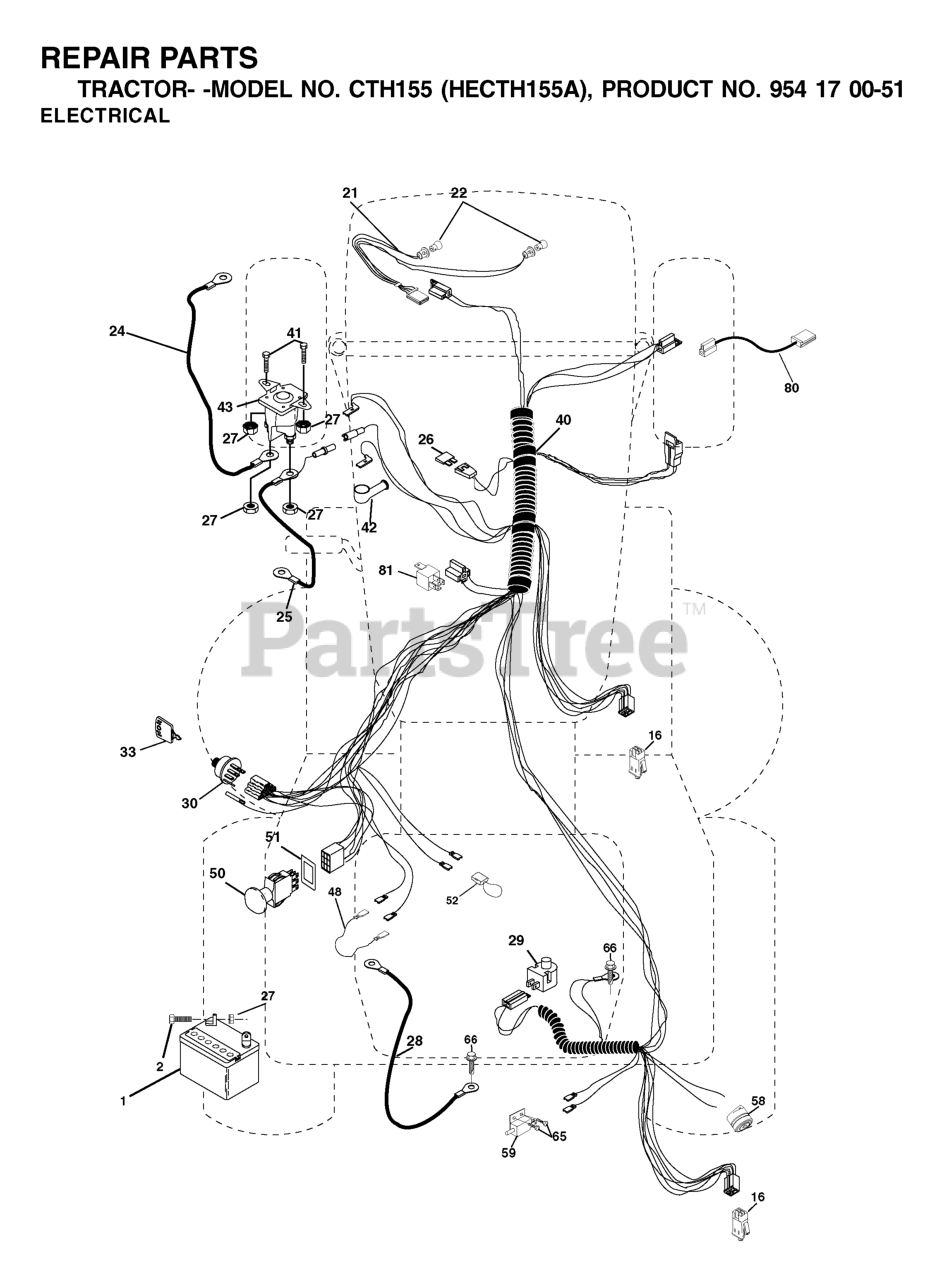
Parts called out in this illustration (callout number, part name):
1	Battery 12 Volt 25 Amp
2	BOLT.HEX.1/4.X.3/4.DICHROMATE
16	SWITCH INTERLOOK PUSH-IN
24	BATTERY CABLE GT
25	CABLE BATTERY
26	FUSE 20AMP
27	NUT
28	CABLE GROUND
29	PLUNGER SWITCH (COLOR:OLIVE)
30	IGNITION SWITCH
33	KEY MLD GEN DELTA
41	BOLT
42	TERMINAL COVER
43	SOLENOID
48	ADAPTER.AMMETER
50	RP.PTO.SWITCH.8 TERMINAL.BLACK
51	FRAME RETAINING RING
52	WIRE PROTECTION LOOP
58	BUZZER
59	.WITCH.FULL BAGGER.INDICATOR
80	HARNESS, CLUTCH
81	RELAY.ASSY.T
